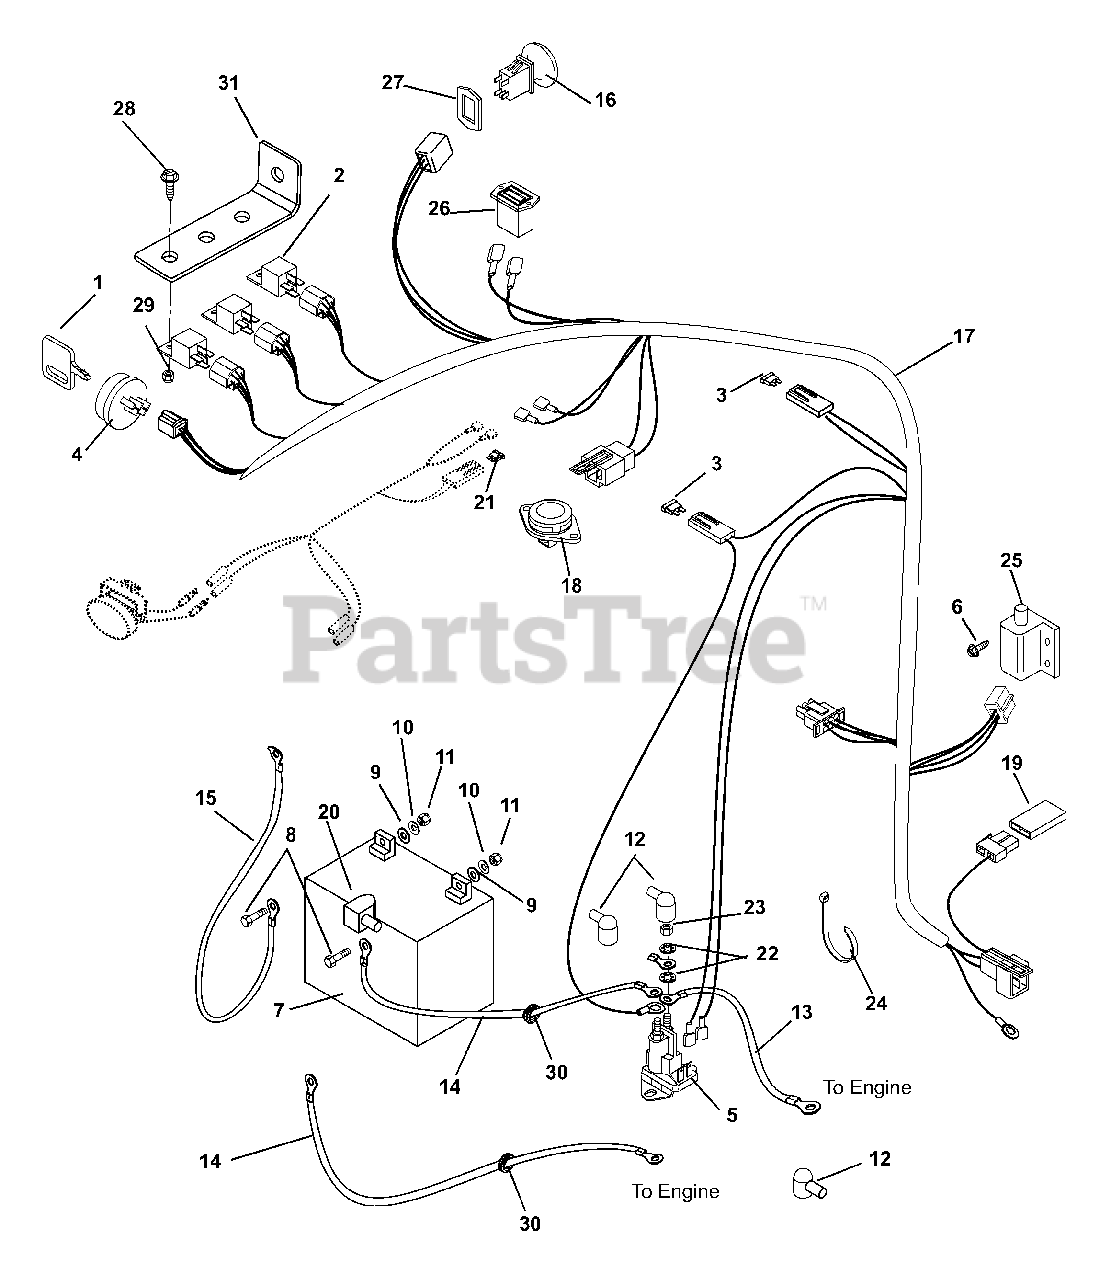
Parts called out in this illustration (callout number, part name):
1	KEY -W/CAP
2	RELAY,SEALED W/DIODE
3	FUSE-25 AMP ATC TYPE
4	KEY SWITCH
5	SOLENOID
6	@SCR-TAP 10-24X.50 HWH TR YWZC
7	BATTERY, 300 CCA 10U1L
7	BATTERY W/ TUBE
8	@BLT-HEX .25-20X.75 GR5 YWZC
9	@WSHR-FL-STL.281X.62X.065 YWZC
10	@WSHR-LK .25X.062 REG YWZC
11	@NUT-HEX .25-20 YWZC
12	BOOT, EYELET TERMINAL
13	STARTER CABLE 6.75"
14	STARTER CABLE 16"
14	START CABLE 22"
15	GROUND CABLE .31X22.00X.31
16	SWITCH, CLUTCH
17	WIRE HARNESS, ZT XL/ZOOM CE
18	SWITCH- SNAP MTG N.O.
19	DIODE, CONNECTOR SHELL
20	INSULATOR
21	FUSE 20AMP
22	WSHR-LOCK INT .31 YWZC
23	NUT-JAM .31-24 YWZC
24	CABLE TIE LG 5-1/2
25	SWITCH- DOUBLE POLE N.O./N.O.
25	SWITCH- SINGLE POLE N.O.
26	HOURMETER-QUARTZ 80VDCMAX
27	SHIM,PTO SW (DELTA #972301)
28	@SCR-MCH 10-24X.50 HWH YWZC
29	@NUT-LK-NYL 10-24 W/INSRT YWZC
30	GROMMET 1.0ID X 1.38 OD
31	BRACKET, RELAY
